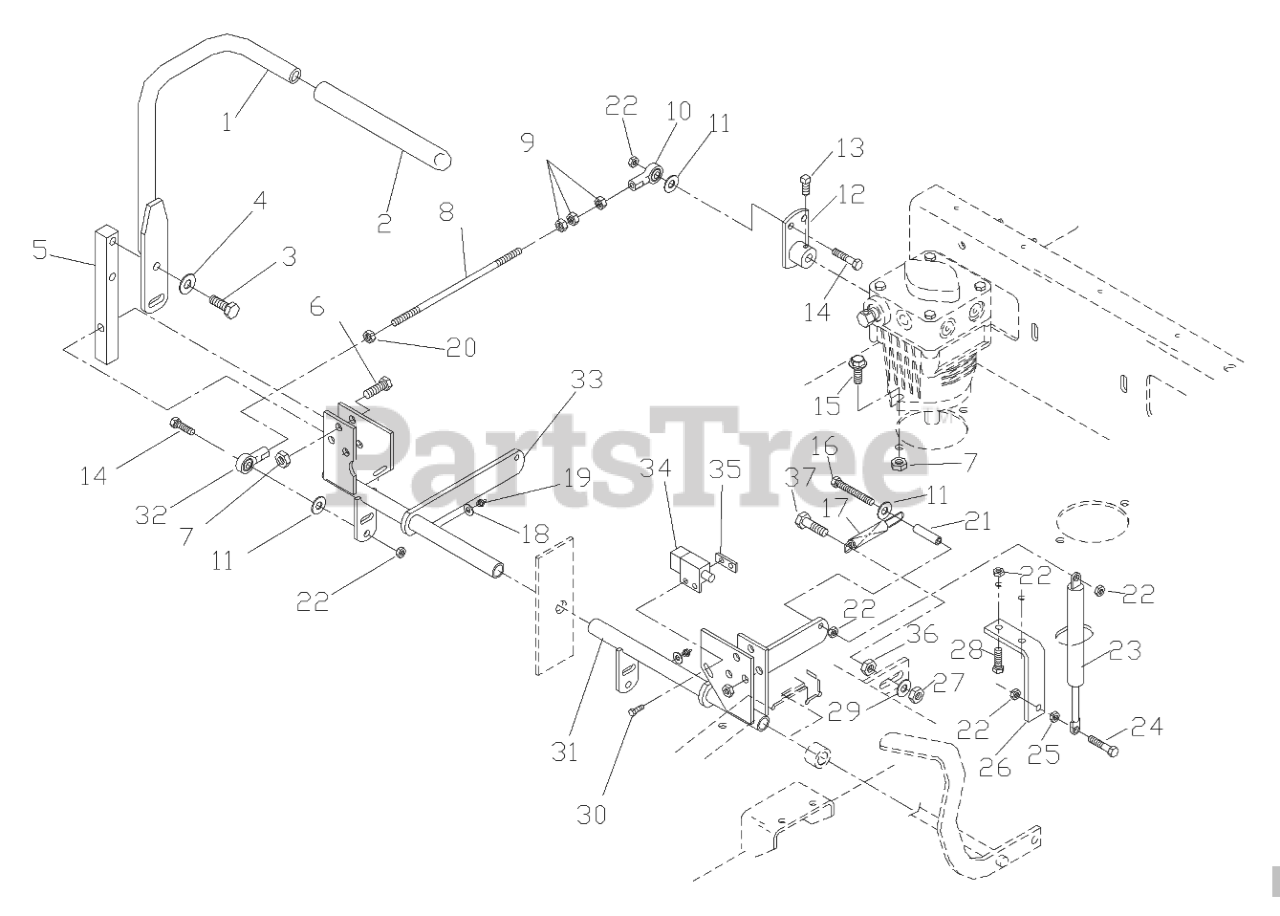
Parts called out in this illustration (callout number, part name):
1	CONT. LEVER
3	HCS 3/8C X 1
4	3/8 SPRING WASHER
5	ARM CONT. SHAFT
6	HCS 3/8C X 1 1/2
7	NUT 3/8C CTR. LOCK
8	PUMP CONTROL LINK
10	BALL JOINT RT.
11	5/16 FLAT WASHER
12	PUMP LEVER
13	5/16C X 5/8 "V" POINT
14	HCS 5/16C X 1
15	HCS 3/8C X 1
16	TAPBOLT 5/16C X 2.25
17	REV. DETENT SPRING
19	ZERK
20	NUT 5/16F LH.
22	5/16C CTR. LOCK
24	HCS 5/16C X 1.25
25	5/16C WHIZ NUT
26	BRACKET "L"
27	3/8C NYLOC
28	HCS 5/16C X 3/4
29	3/8 FLAT WASHER
30	SCREW #10-24 X 5/8
31	CONTROL WLDMT. LEFT
32	BALL JOINT LH.
33	CONTROL WLDMT. RIGHT
35	TAPPED PLATE
36	3/8C WHIZ NUT
37	HCS 3/8C X 2
38	HOSE CLAMP
